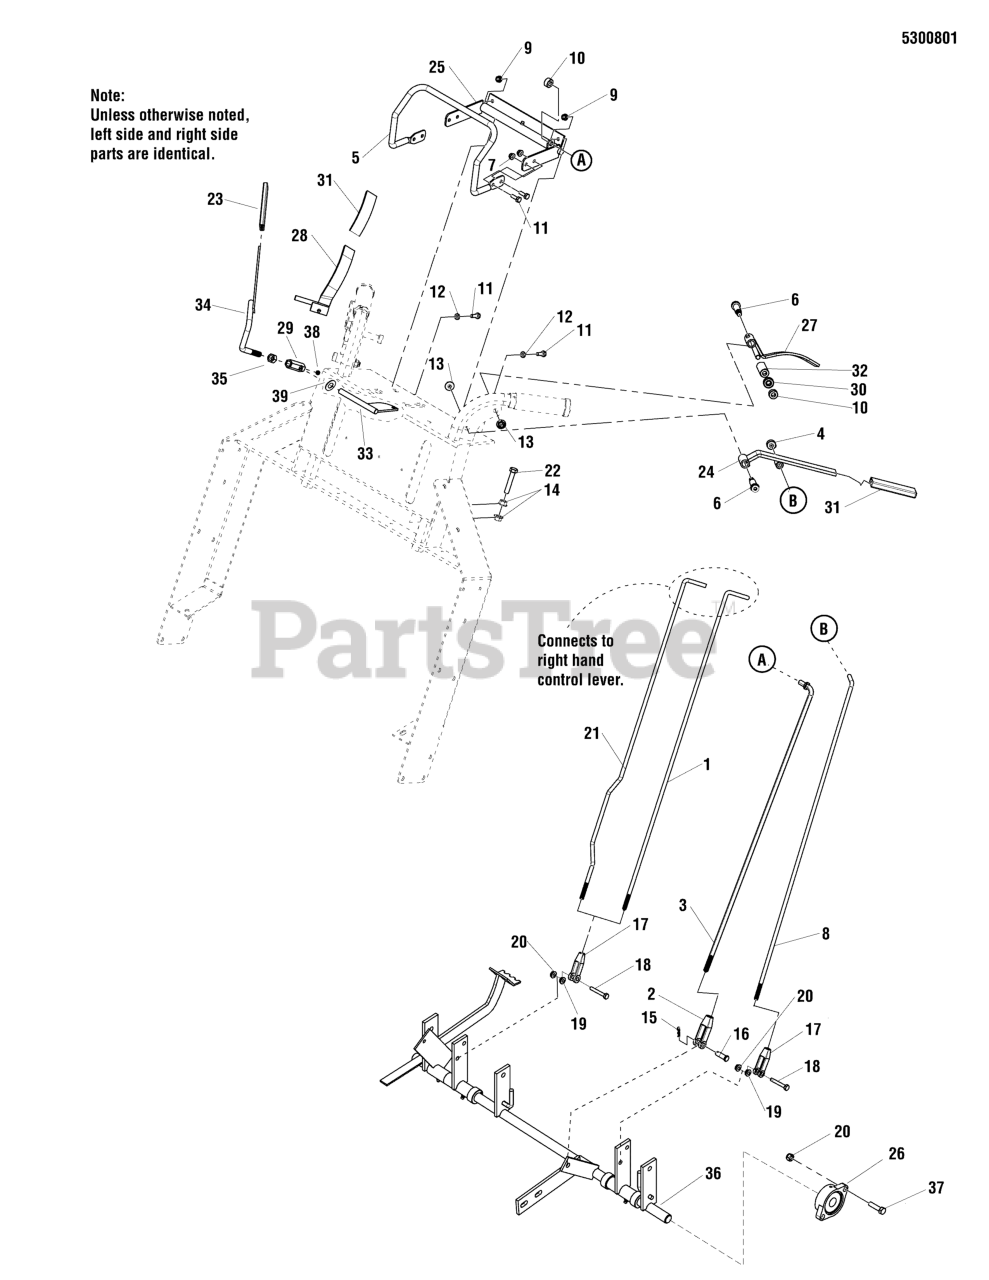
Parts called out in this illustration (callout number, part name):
1	ROD, DDS REVERSE CONTROL - RH
2	CLEVIS, 3/8-24, PLASTIC
3	ROD, CRUISE CONTROL W/WASHER
4	SET COLLAR, 5/16"
5	BAR, SPEED CONTROL - DUAL DRIVE
6	SHOULDER BOLT, 1/2" X 1-1/2"
7	NUT, 1/4-20 HEX NYLOCK FLANGE
8	ROD, DDS REVERSE CONTROL - LH
9	NUT, 1/4-20 HEX SERR. FLANGE
10	COLLAR, 3/8" SET
11	BOLT, 1/4-20 X 3/4" GD5
12	WASHER, 1/4 SAE
13	NUT, 3/8-16 HEX NYLOCK FLANGE
14	NUT, 3/8-16 HEX LG. SERR FLG
15	PIN, HAIR, .0585 X 1-1/8
16	PIN, CLEVIS, 3/8" X 1-1/8"
17	CLEVIS, 5/16-24, STEEL, CLEAR ZINC
18	BOLT, 5/16-18 X 2
19	NUT, 5/16-18 HEX
20	NUT, 5/16-18 HEX NYLOCK FLANGE
21	ROD, REVERSE - RH
22	BOLT, 3/8-16 X 1-3/4" TFL
23	GRIP, VINYL, 1/2 X 4"
24	WELD, HAND CONTROLS, DDS
25	WELD, SPEED CONTROL, DDS
26	BEARING, FLANGE
27	WELD, THUMB CONTROLS, DDS - LH
28	WELD, THUMB CONTROLS, DDS - RH
29	ADJUSTER, LINKAGE
30	BEARING, R6-2RS
31	GRIP, FOAM, 1/4 X 1 X 4.1
32	SPACER, .38 X .50 X 1.25, CZ
33	WELD, OPERATOR PRESENCE HANDLE - RED
34	WELD, OPERATOR PRESENCE, RH
35	NUT, 3/8-16 HEX
36	WELD, DDS CONTROL SHAFT
37	BOLT, 5/16-18 X 1" GD5 YZ
38	SET SCREW, 3/8-16 X 3/8
39	WASHER, 3/8 SAE
